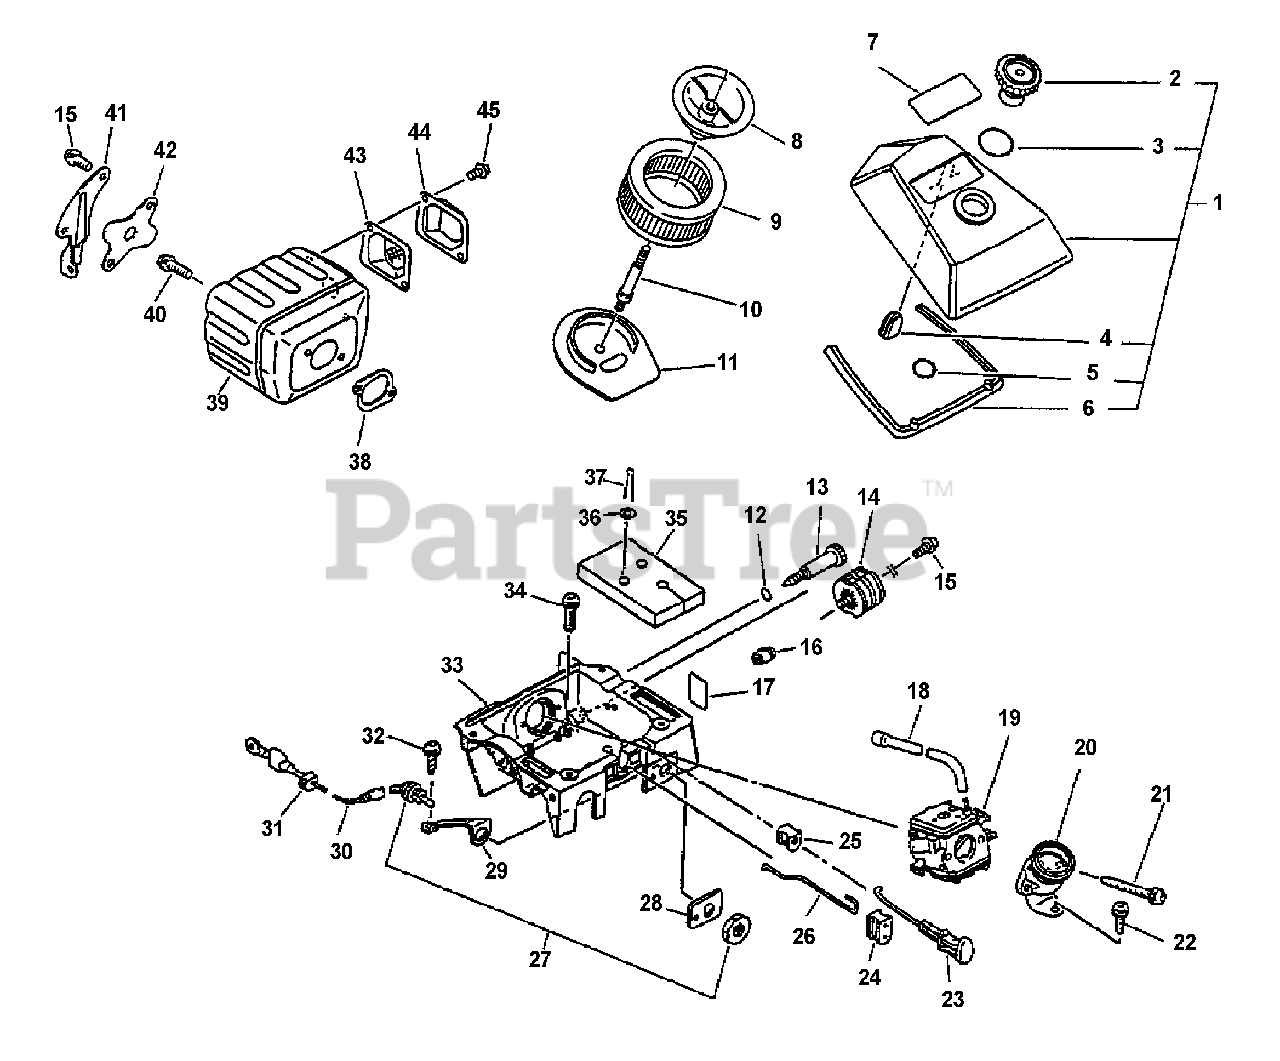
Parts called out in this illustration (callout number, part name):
1	AIR FILTER COVER ASSY
2	THUMBNUT
3	O-RING - 21
5	O-RING - 11
6	SEAL
7	LABEL - MODEL CS-6700
8	COVER, AIR FILTER
9	AIR CLEANER ASSY
10	STUD
11	BRACKET, AIR CLEANER
12	O-RING - 7
13	SCREW, IDLE ADJUST
15	SCREW - 5X14
17	LABEL - IDLE
18	PIPE - IMPULSE
19	CARBURETOR HDA-151A
20	ADAPTOR, INTAKE
21	SCREW - 5X55
22	SCREW - 5X14
23	ROD, CHOKE
24	GUIDE, THROTTLE ROD
25	GROMMET
26	ROD, THROTTLE
27	IGNITION SWITCH ASSY
28	LABEL - STOP
29	TERMINAL - GROUND
30	LEAD - GROUND
32	SCREW - 4X10
33	CASE, CARBURETOR
34	SCREW - 5X20
37	PIN, SPLIT - 3X18
38	GASKET, EXHAUST
39	MUFFLER
40	SCREW - 5X20
41	BRACKET, MUFFLER
42	COVER, MUFFLER
43	SCREEN, SPARK ARRESTOR
44	GUIDE, EXHAUST
45	SCREW - 4X10
